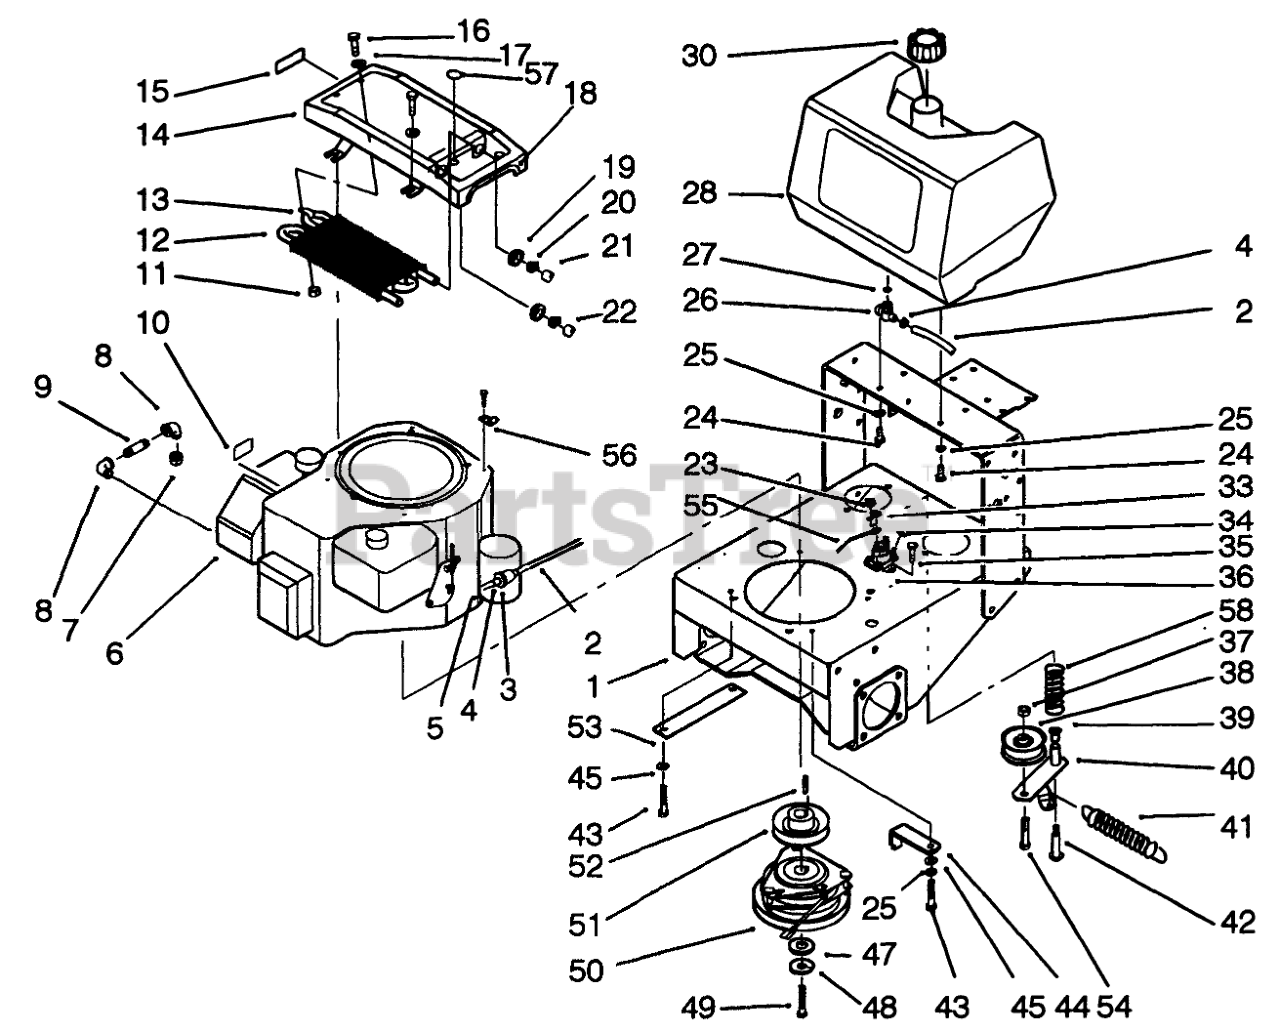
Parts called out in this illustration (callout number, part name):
1	Frame
2	HOSE-FUEL
3	FILTER-FUEL
4	CLAMP-HOSE
5	HOSE-FUEL
6	Engine-14 H.P. Kohler
7	CAP-PIPE
8	ELBOW-STREET, 90 DEG
9	NIPPLE
10	DECAL-SURFACE, HOT
11	NUT-LOCK, NI
12	Cooler-Oil
13	CLAMP-R
14	Mount-Cooler
15	DECAL-FUEL SHUT OFF
16	SCREW-HH
17	WASHER-FLAT
18	TRIM-MOUNT, COOLER
19	GROMMET
20	CLAMP-HOSE
21	HYDRAULIC HOSE ASM
22	HYDRAULIC HOSE ASM
23	NUT-LOCK
24	SCREW-HH
25	WASHER-LOCK
26	VALVE-FUEL
27	O-RING
28	FUEL TANK
30	GAS CAP ASM
33	NUT-KEPS
34	NUT-KEPS
35	SCREW-HWH
36	Solenoid
37	NUT-LOCK, NI
38	PULLEY
39	BUSHING-FLANGE
40	Idler Assembly
41	SPRING
42	BOLT-WHEEL
43	SCREW-HH
44	Retainer-Clutch
45	WASHER-PLAIN
47	WASHER-CLUTCH
48	WASHER-LOCK
49	SCREW-CLUTCH
50	CLUTCH/BRAKE
51	Pulley
52	KEY-SQUARE
53	Guard-Pulley
54	SCREW-HH
55	WIRE-SOLENOID/STARTER
56	R-Clamp
57	PLUG-PLASTIC
58	SPRING-COMPRESSION
